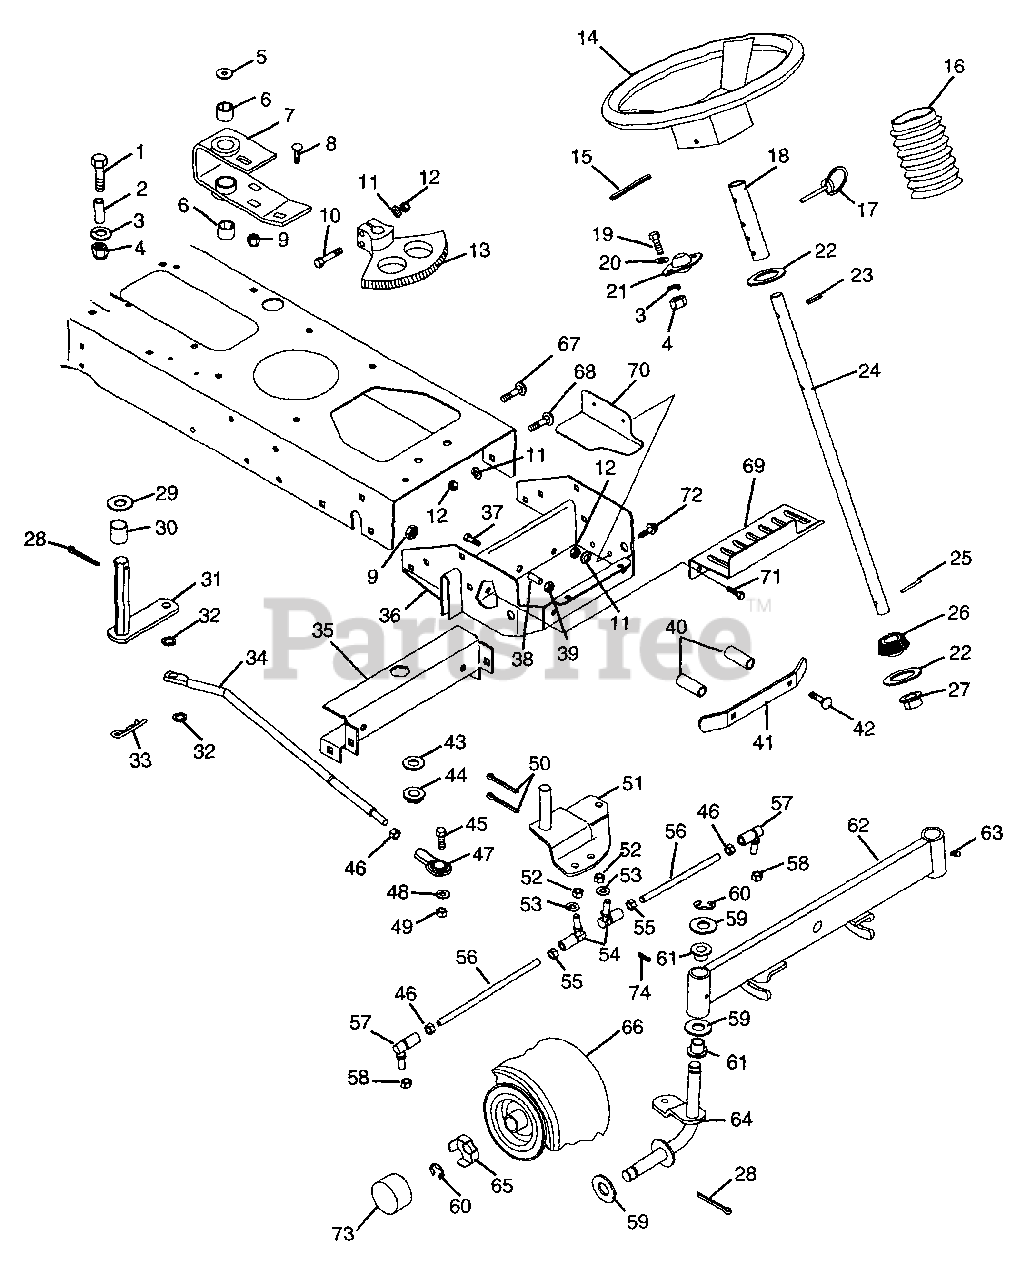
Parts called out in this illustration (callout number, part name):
1	BLT-HEX .31-18X1.50 PL GR2
2	SPACER .344X.500X.875
3	WSHR-LK .312X.097 PL HVY
4	NUT-HEX .312-18
5	WSHR-FL-STL .880X1.250X.062
6	BSHG-SLV .750X1.000X.750 HX SB
7	STEERING BRACKET
8	BLT-RDHDSQSHNK .38-16X1.00 PL
9	NUT-LK-CTR .375-16 GR A PL
10	BLT-HEX .31-18X1.75 PL GR2
11	WSHR-LK 2X.02 MED
12	NUT-HEX .375-16
13	STEERING BEVEL GEAR
14	STEERING WHEEL 13"
15	PIN-ROLL .250X1.75
17	PIN-DET W/RING .25X1.00
18	TUBE .754 X .999 X 5.00
19	BLT-HEX .31-18X.75 PL GR5
20	WSHR-FL-STL.312X.734X.065PL
21	BRG-FLG .751X2 HOLESX.81
22	WSHR-FL-STL .754X1.125X.062 PL
23	PIN-ROLL .188X1.13
24	STEERING COLUMN
25	PIN .249X1.125 DRIV-LOK SP
26	PINION GEAR-STEERING
27	BSHG-FLG .750X1.093X.625X1.375
28	PIN-COTR .18X1.25 PL
29	WSHR-FL-STL .875X1.250X.075
30	SPACER .900X1.017X1.090
31	ARM & SHAFT
32	WSHR-FL-STL .520X.827X.062 YZ
33	PIN-HAIR INT .08X.38X1.42 YWZC
34	DRAG LINK
35	STEERING PIVOT CHANNEL
36	FRONT AXLE SUPPORT
37	BLT-HEX .50-13X1.50 PL GR5
38	SPACER .531X.748X.524
39	NUT-LK-CROWN .50-13 GR C PL
40	SPACER .512X.748X2.50
41	FRONT BUMPER
42	BLT-RDHDSQNK .38-16X3.50 GR5PL
43	WSHR-FL-STL.656X1.312X.095 PL
44	FLANGE BUSHING
45	BLT-HEX .38-16X1.25 PL GR5
46	NUT .375-24 PL
47	ROD END, .38 RH
48	WSHR-FL-STL .382X.812X.062
49	NUT-LK TOP .375-16 GR C YWZC
50	PIN-COTR .12 X 1.25 PL
51	STEERING PIVOT
52	NUT-LK-CTR .375-24
53	WSHR-FL-STL .390X.750X.125 PL
54	BALL JOINT-LH
55	NUT L.H. THD .375-24 PL
56	TIE ROD
57	BALL JOINT-RH
58	NUT-LK .375-24 PL
59	WSHR-FL-STL .755X1.375X.093
59	WSHR-FL-STL .755X1.375X.062 PL
60	RG-RTNG-EXT .750X.050
61	BSHG-SLV .750X.814X .750 BRZ
61	BSHG-FLG .750X1.000X.750X1.250
62	FRONT AXLE
63	SPIN DRIVE ZERK FITTING
64	SPINDLE LH
64	SPINDLE RH
65	SPINDLE CUP
66	T/WHL ASSY 13X5.00-6
66	RIM
66	TIRE
66	T/WHL ASSY 15X6.00-6
66	BSHG .75 BORE
67	BLT-RDHDSQSHNK .38-16X1.00 PL
68	BLT-RDHDSQNK .38-16X.75 SHT PL
69	BAFFLE- HEAT (ENG.COOLING AIR)
70	DEFLECTOR PLATE
71	BLT-HEX .38-16X.75 PL GR5
72	SCR-TAP 12-24X.50 HWH PL TR
73	HUB CAP
74	PIN-ROLL .250X1.25
